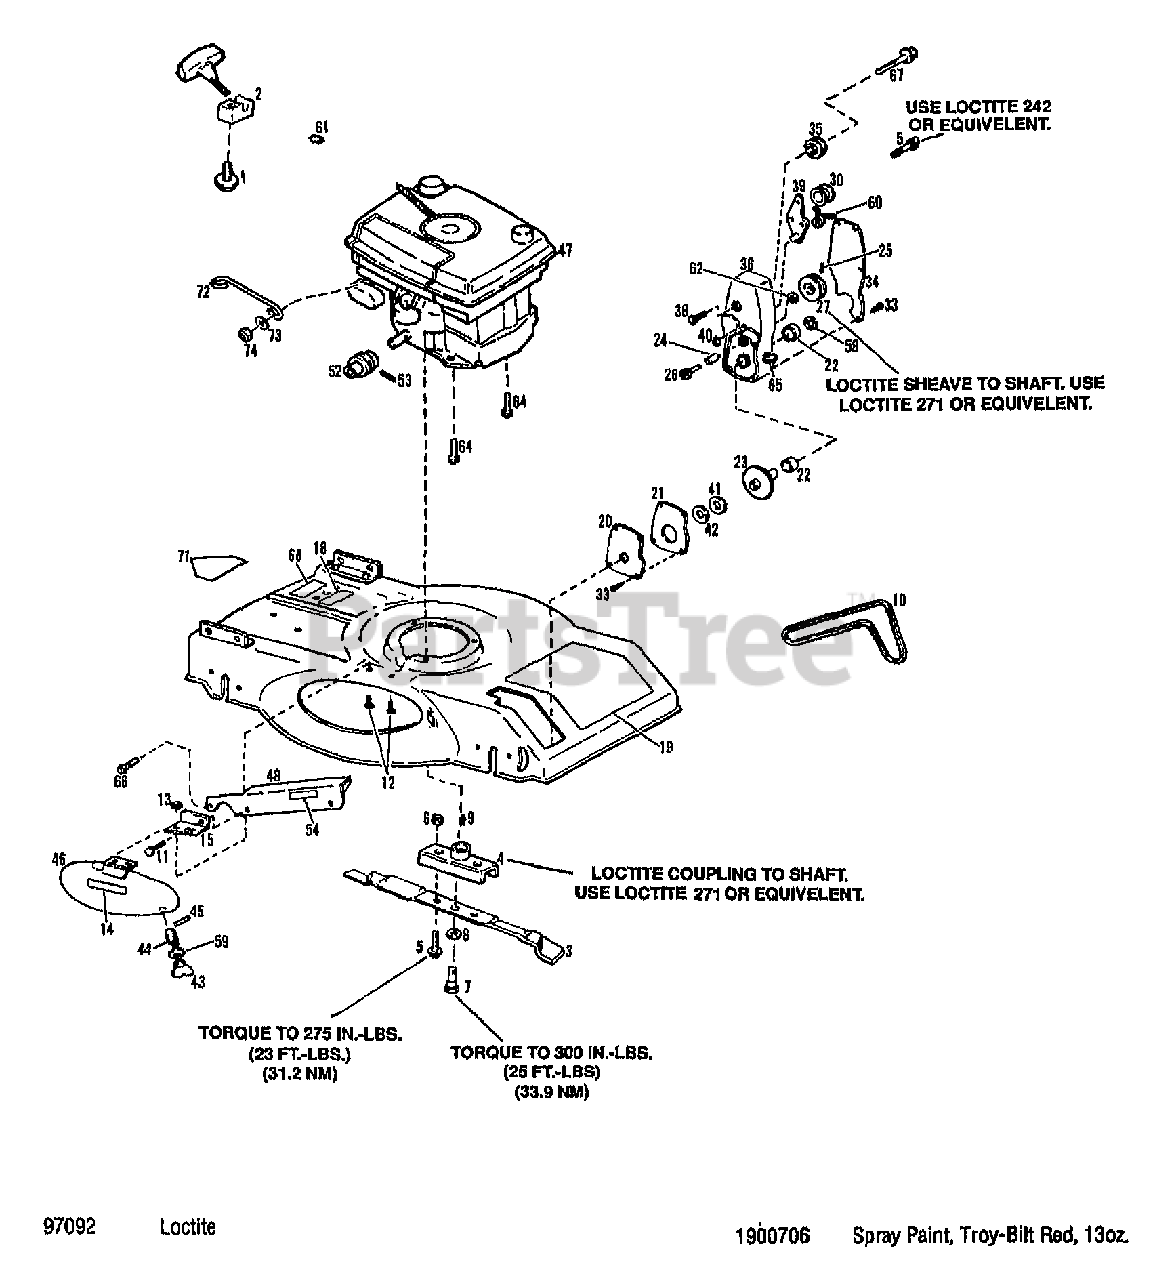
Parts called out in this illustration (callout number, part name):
1	SCR-HFLK 1/4-20X1.0 THFRM
2	GUIDE-ROPE
3	BLADE-22" MULCHER
4	ASSM-BLADE COUPLING
5	SCR-HH 3/8-16X1.0 G5 ZP
6	NUT-LOCK 3/8-16
7	SCR-SHOULDER
8	WASHER-LK .5
9	KEY-WOODRUFF .156X.625
10	BELT-DRIVE
11	SCR-SHOULDER
12	SCR-CARR 1/4-20X.375
13	NUT-HF/LK 1/4-20 ZP
14	DECAL-CAUTION
15	BRKT-SUPPORT
18	DECAL-CUTTING HEIGHT
19	DECAL-LOGO
19	DECAL-LOGO MULCHER 22"
20	COVER-GEAR CASE BOTTOM
21	GASKET-GEAR CASE
22	BEARING-BRONZE
23	ASSM-GEAR SHAFT
24	BEARING-BRONZE
25	PIN-DRIVE .218X1.12
26	ASSM-STEEL PINION SHAFT
27	SHEAVE
30	IDLER-FLAT
33	SCR-HW M10-24X.5 STH ZP
34	COVER-GEAR CASE TOP
35	SHEAVE
36	ASSM-GEAR CASE
38	SCR-SHOULDER
39	ASSM-IDLER ARM
40	NUT-PUSH 3/8 ZP
41	WASHER-1.5X.755X.062
42	WASHER-FELT
43	PIN-CHUTE LOCK
44	SPRING-COMPRESSION
45	PIN-ROLL .093 DIAX.62
46	COVER-DISCHRG W/DEC (INCL. 12-14, 43-45, 59)
47	TECUMSEH ENGINE 5 H.P. MODEL OVRM50-52620B
47	TECUMSEH ENGINE 5.5 H.P. MODEL OVRM55-52620C
48	ASSM-BELT COVER
52	SHEAVE
53	PIN-ROLL
54	DECAL-FRONT WHEEL DRIVE
58	RING-GRIP EXT .5 ID
59	WASHER-.75X.312X.065 ZP
60	SPRING-TORSION
61	STOP-STARTER ROPE
62	WASHER-SHIM
64	SCR-HH 3/8-16X1.0 THDFM
65	FITTING-GREASE 1/4-28X2.00
66	SCR-FLANGE 1/4-20X3/4 GR5
67	SCR-HH 5/16-18X.875 G5 ZP
68	DECAL-U.S.A.
71	DECAL-OPEI CAUTION
72	SUPPORT-CHUTE CRANK
72	SUPT-THROTTLE CONTROL
73	WASHER-FLAT 1/4 SAE
74	NUT H/LK 1/4-28
